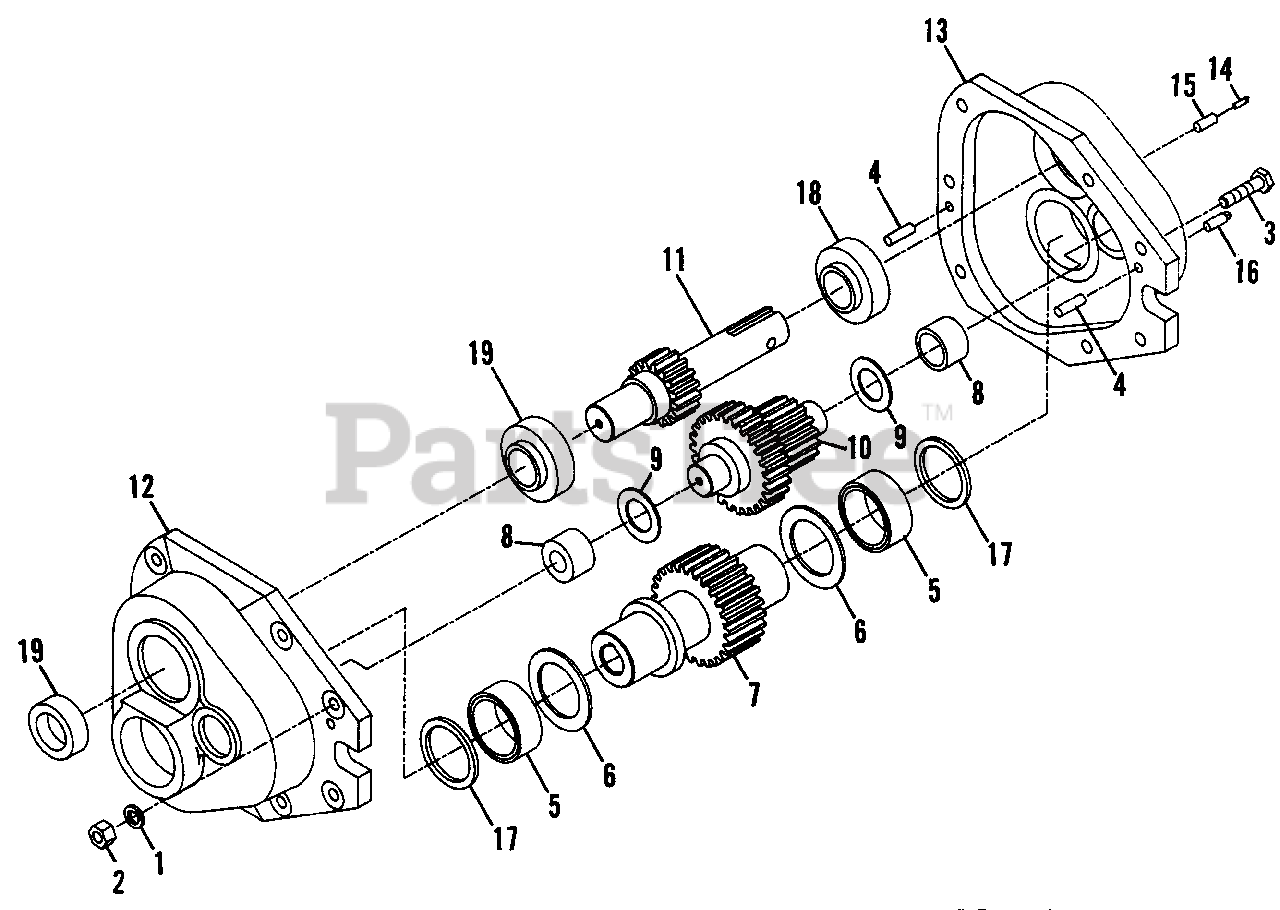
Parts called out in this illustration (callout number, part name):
1	LOCKWASHER, 5/16 regular
2	NUT, Hex, 5/16
3	CAPSCREW, Hex Hd., 5/16 18 x 1-1/4
4	PIN, Dowel, 1/4 dia x 1/2 Ig.
5	BEARING, 1-1/2 x 1-7/8 x 3/4
6	BEARING, Thrust race .090 thick
7	GEAR, Output
8	BEARING, 7/8 x BG-1/8 x 3/4
9	BEARING, Thrust race .060 thick
10	GEAR, Idler
11	GEAR, Input
12	GEARBOX, Snowblower-front
13	GEARBOX, Snowblower-rear
14	VENT, Relief
15	BUSHING, 1/4-male, 1/8-female
16	PLUG, Pipe, sq. hd. 1/4 NPT
18	BEARING, Ball, 1.00 bore w/o collar
19	BEARING. Ball. 1.00 bore w/collar
